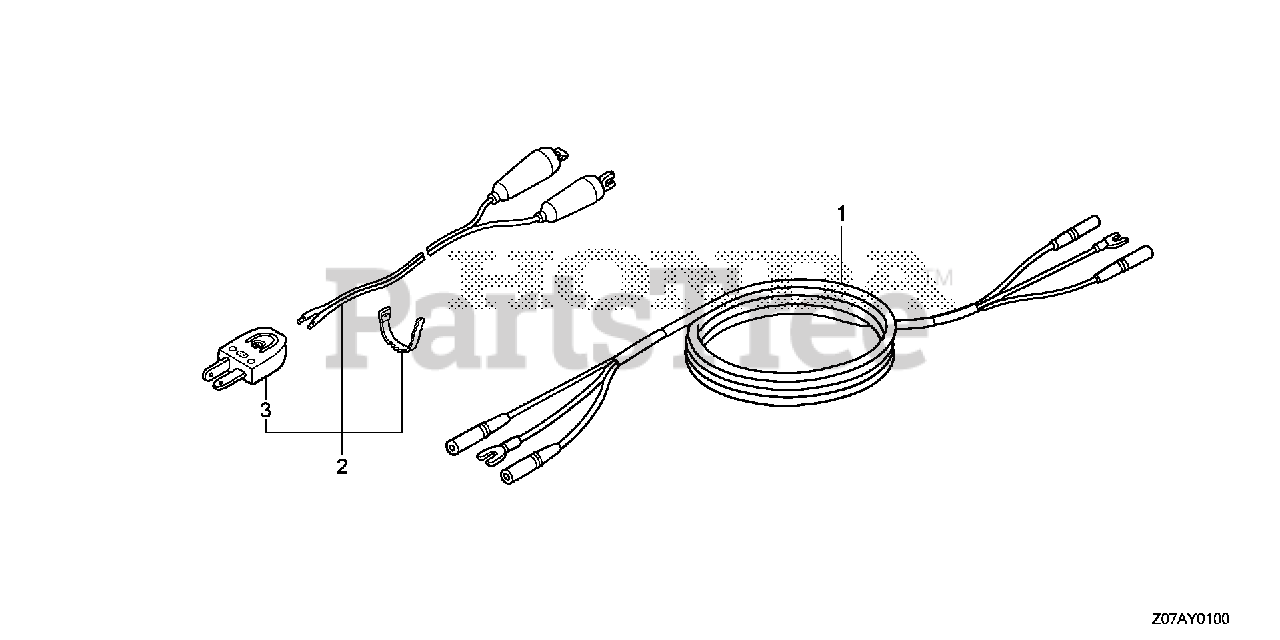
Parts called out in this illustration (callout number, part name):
1	CABLE KIT, PARALLEL
2	WIRE ASSY., CHARGE (2M)
3	PLUG ASSY., RECEPTACLE
